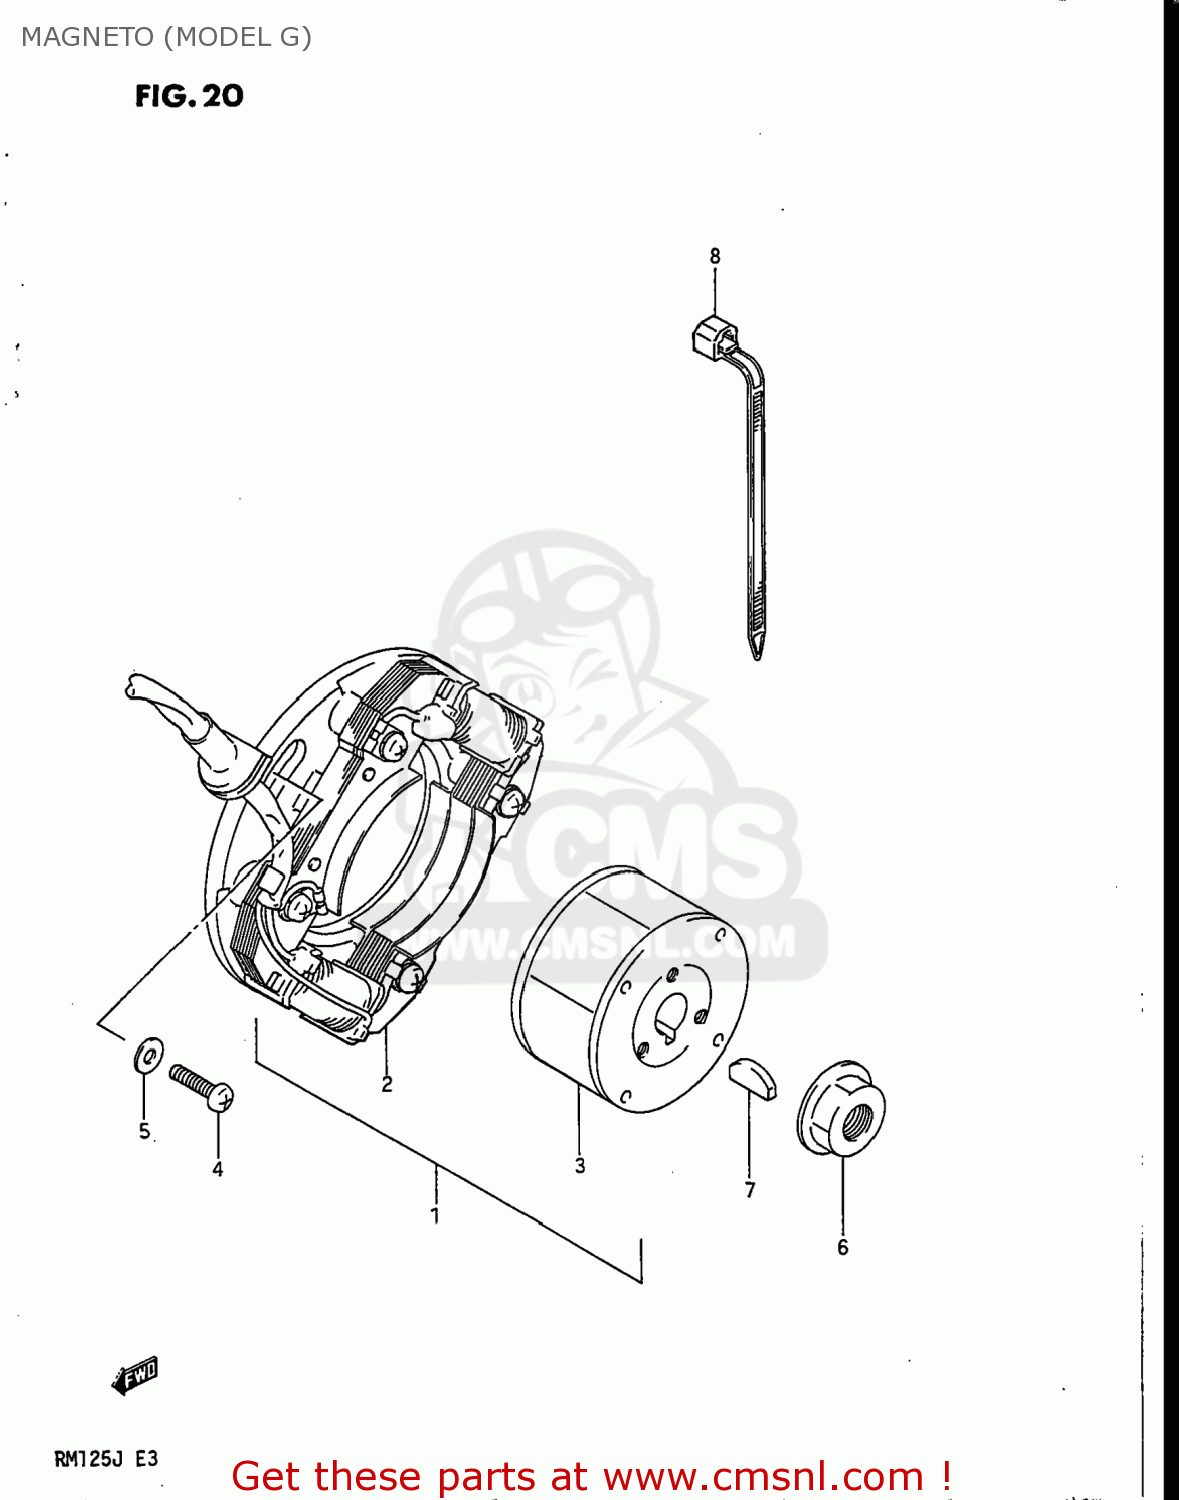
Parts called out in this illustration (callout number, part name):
1	MAGNETO ASSEMBLY
2	STARTER ASSY
3	ROTOR
4	SCREW
5	WASHER
6	NUT
7	KEY 4MM
8	CLAMP(L:125)
